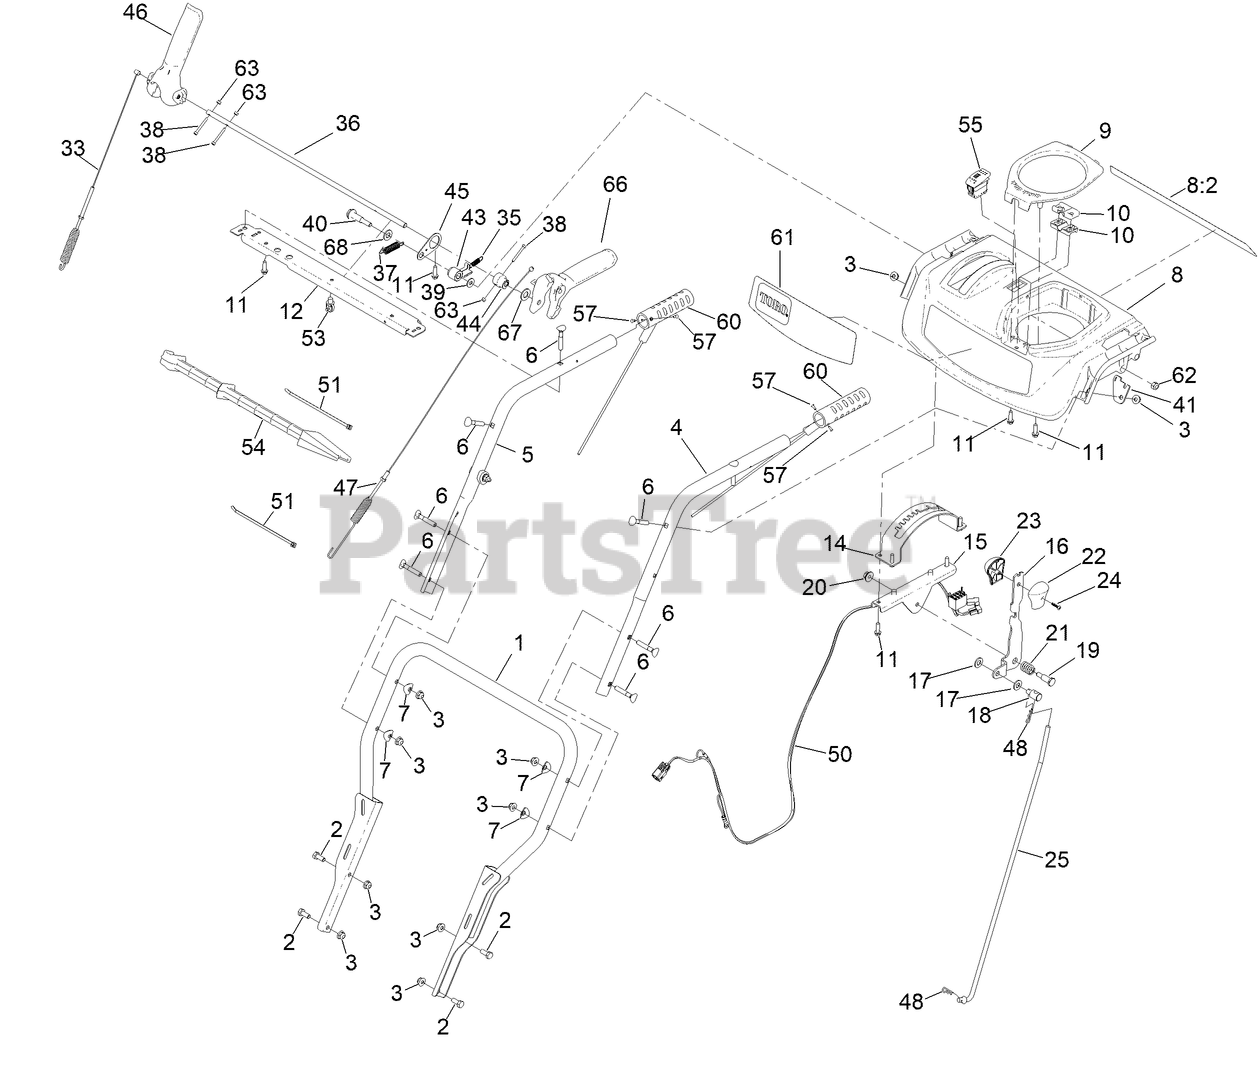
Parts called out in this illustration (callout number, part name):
1	LOWER HANDLE ASM
2	SCREW-HH
3	NUT-HF
4	HANDLE-UPPER, LH
5	HANDLE-UPPER, RH
6	SCREW-HANDLE
7	WASHER-CUP
8	CONTROL PANEL ASSEMBLY
8:2	DECAL-SAFETY
9	COVER-QUICKSTICK
10	SUPPORT-ROD
11	SCREW-PLASTITE, HWH
12	BRACE-CONSOLE
14	GATE-SHIFT
15	BRACKET-SHIFT
16	SELECTOR-SPEED
17	WASHER-FLAT
18	TRUNNION-ROD
19	SCREW-SHOULDER, HH
20	NUT-HF
21	SPRING-COMPRESSION
22	KNOB-SHIFT, LH
23	KNOB-SHIFT, RH
24	SCREW-PPH
25	ROD-SHIFT
33	CABLE-AUGER
35	SPRING-LOCKOUT, HANDLE
36	ROD-LOCKOUT
37	SPRING-RETURN, LEVER
38	SCREW-HSH,SPL
39	WASHER-FLAT
40	SCREW-SHOULDER
41	PLATE-SPRING
43	LATCH, LOCKOUT
44	CAM-LOCKOUT
45	LINK-LOCKOUT
46	LEVER-CONTROL
47	CABLE-TRACTION
48	PIN-HAIR
50	HARNESS-WIRE, LED AND HAND WARMERS
51	TIE-CABLE
53	CLIP-TIE
54	STICK-CLEANOUT
55	SWITCH-ROCKER, ON-NONE-OFF (HEATER)
57	RIVET-POP
60	RED HEATED GRIP
61	DECAL-CONSOLE
62	NUT-HEX
63	NUT-LOCK ROHS
66	LEVER-CONTROL
67	WASHER-FLAT
68	WASHER-FLAT
